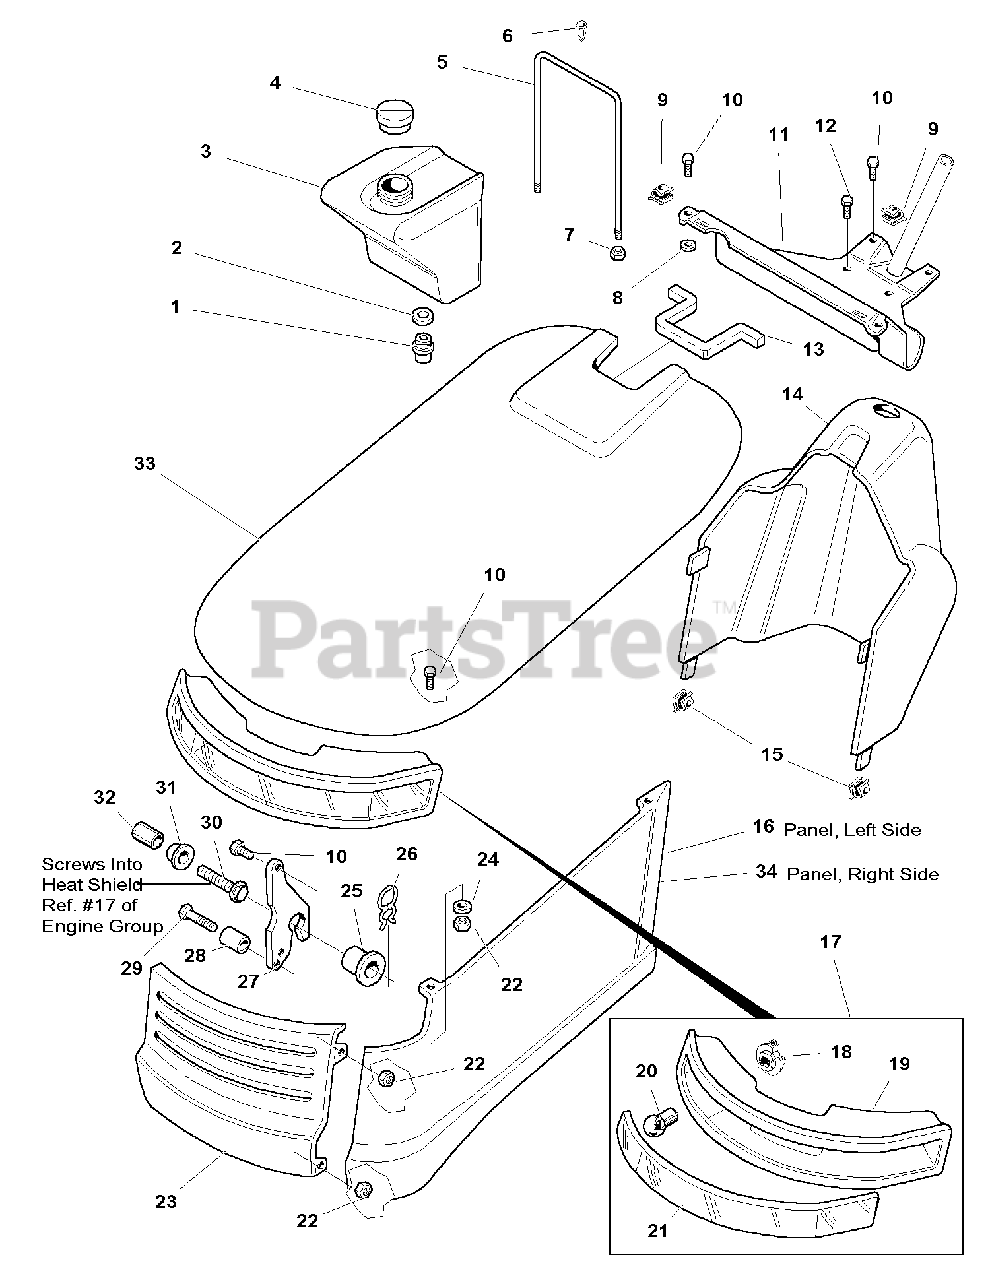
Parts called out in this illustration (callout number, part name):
1	FITTING, Fuel
2	GROMMET, Fuel Fitting
4	CAP, Fuel Tank
6	FASTENER, Plastic, Ratchet
7	NUT, Hex Nylon Lock, 5/16-18
8	WASHER, 1/4
9	PAL NUT, 1/4-20
10	CAPSCREW, Hex Head Whiz Lock, 1/4-20 x 5/8
11	BULKHEAD ASSEMBLY
12	CAPSCREW, Taptite Hex Washer Head, 1/4-20 x 1/2
13	GROMMET, Strip
16	PANEL, Side, LH, Orange
16	PANEL, Side, LH, Red
17	LIGHT BAR ASSEMBLY (Includes Ref. Nos. 18, 19, 20 & 21)
18	SOCKET, Bulb
20	BULB, #1156
22	NUT, Hex, Nylon Lock, 1/4-20
23	GRILLE, Orange
23	GRILLE, Red
24	WASHER, Plain, 1/4
25	SPACER, Plastic, Hood Pivot
26	CLIP, Pivot Spacer Retaining
27	HINGE, Hood
29	CAPSCREW, Hex Head, 1/4-20 x 1-1/2
30	CAPSCREW, Hex Head Whiz Lock, 5/16-18 x 1-1/4
31	SPACER, Steel, Hood Pivot, Grooved
32	SPACER, Steel, Hood Pivot
33	HOOD, Orange
34	PANEL, Side, RH, Orange
34	PANEL, Side, RH, Red
